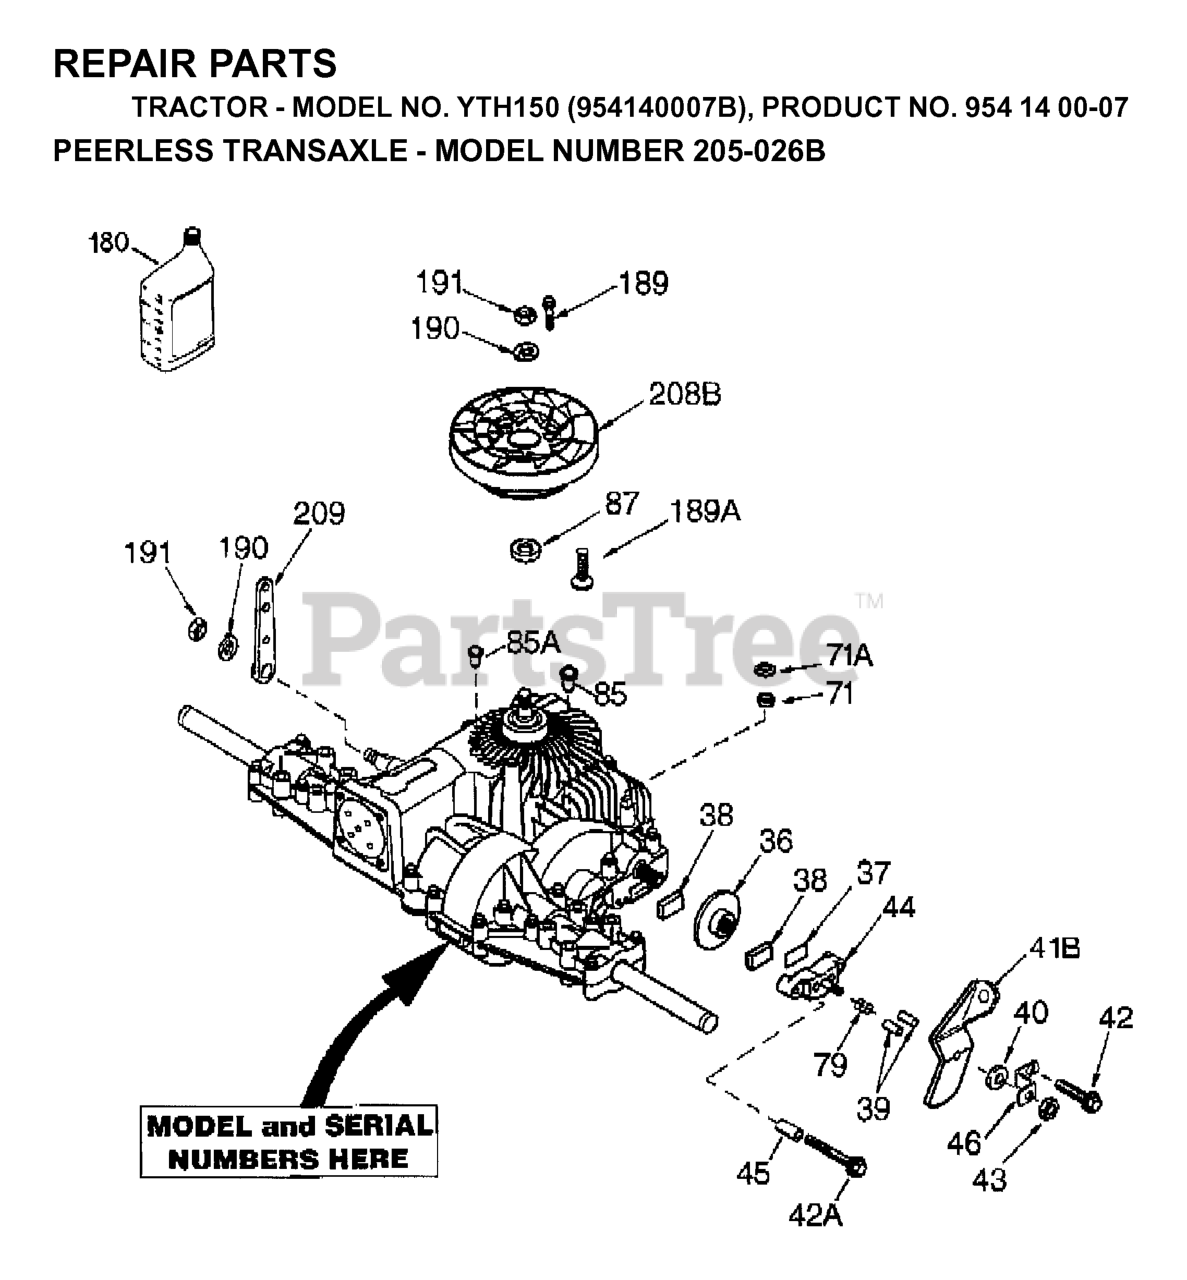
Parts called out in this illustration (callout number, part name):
36	Brake Disk
37	Plate, Brake pad
38	Brake Pad (pkg of 2)
39	Pin, Dowel
40	Washer, Flat
42	Screw, Flanged Hex Head, Thread Forming 1/4-20 x 1-1/4
42A	Screw, 1 /4-20 x 2-1 /4"
43	Lock Nut 5/16-24
44	Holder, Brake pad
45	Spacer (1/2" OD)
71	Seal, Square Cut
79	Piston Assembly
180	Gear Oil 80W90
